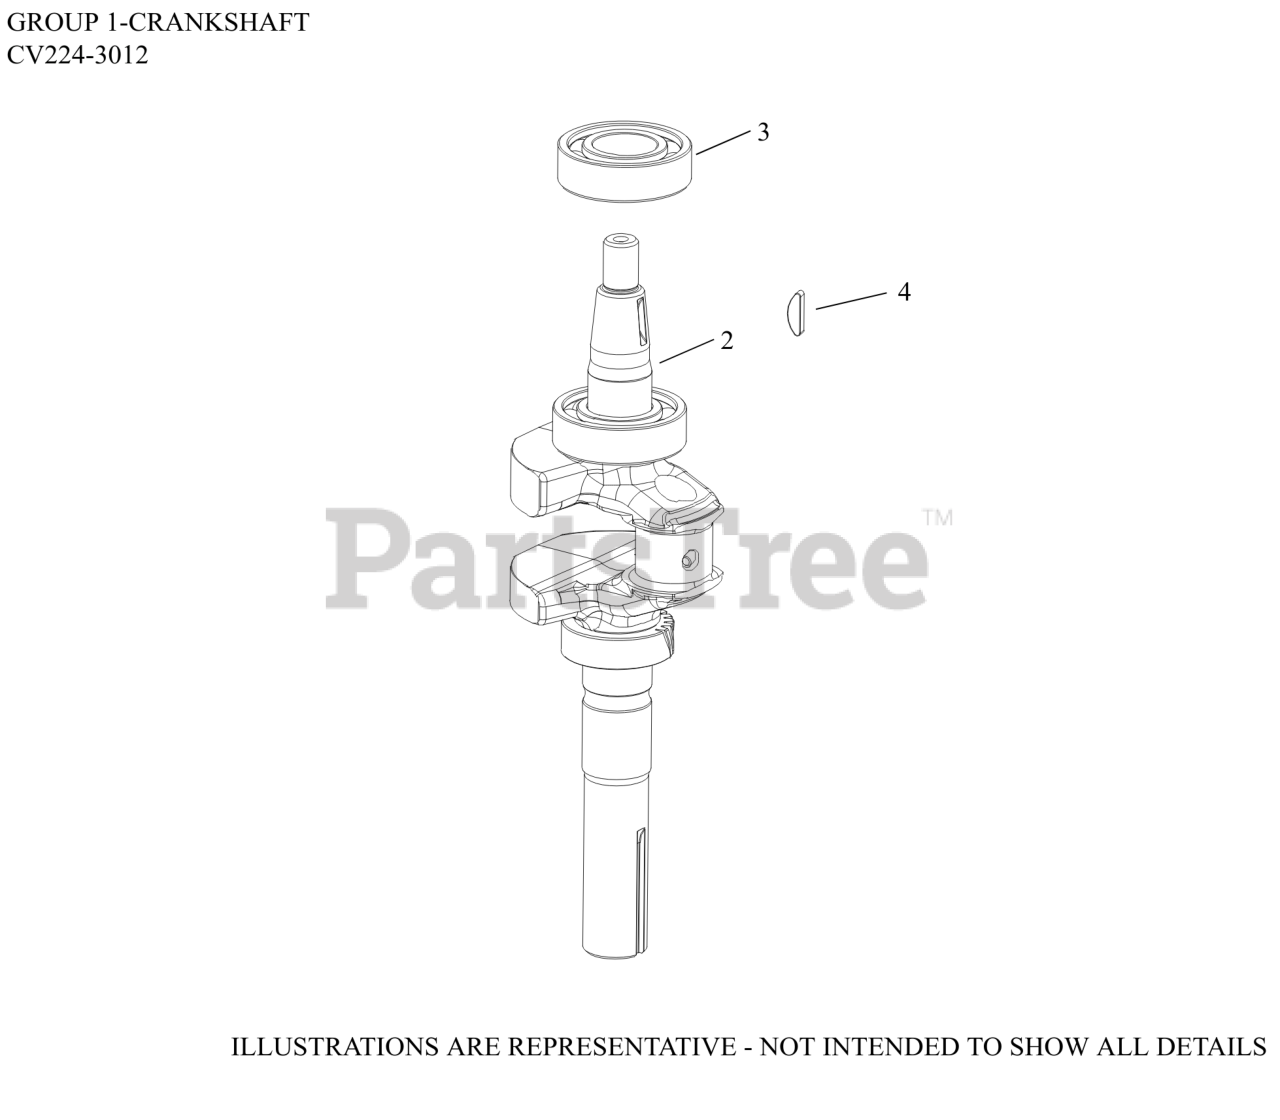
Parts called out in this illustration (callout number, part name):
2	CRANKSHAFT, ASSEMBLY
3	BEARING, BALL
4	KEY, FLYWHEEL
